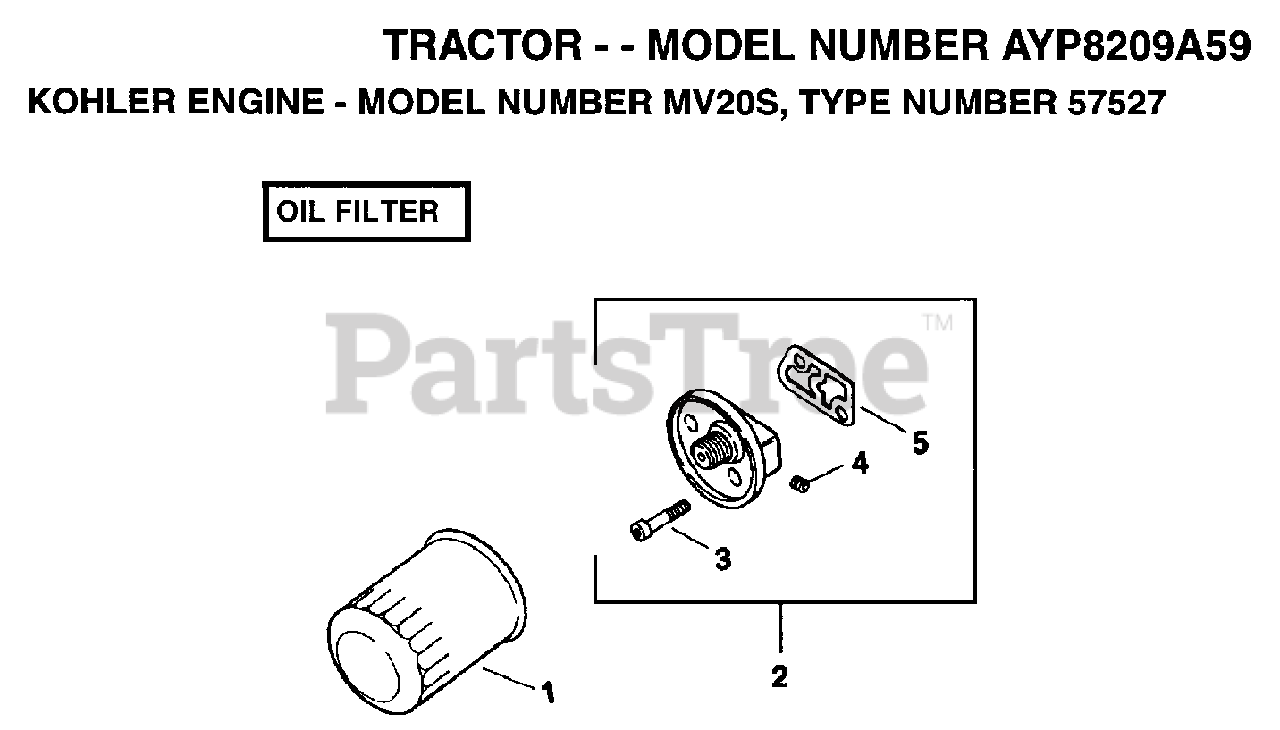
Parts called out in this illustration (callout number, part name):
2	KIT, FILTER ADAPTOR
3	SCREW
4	PLUG
